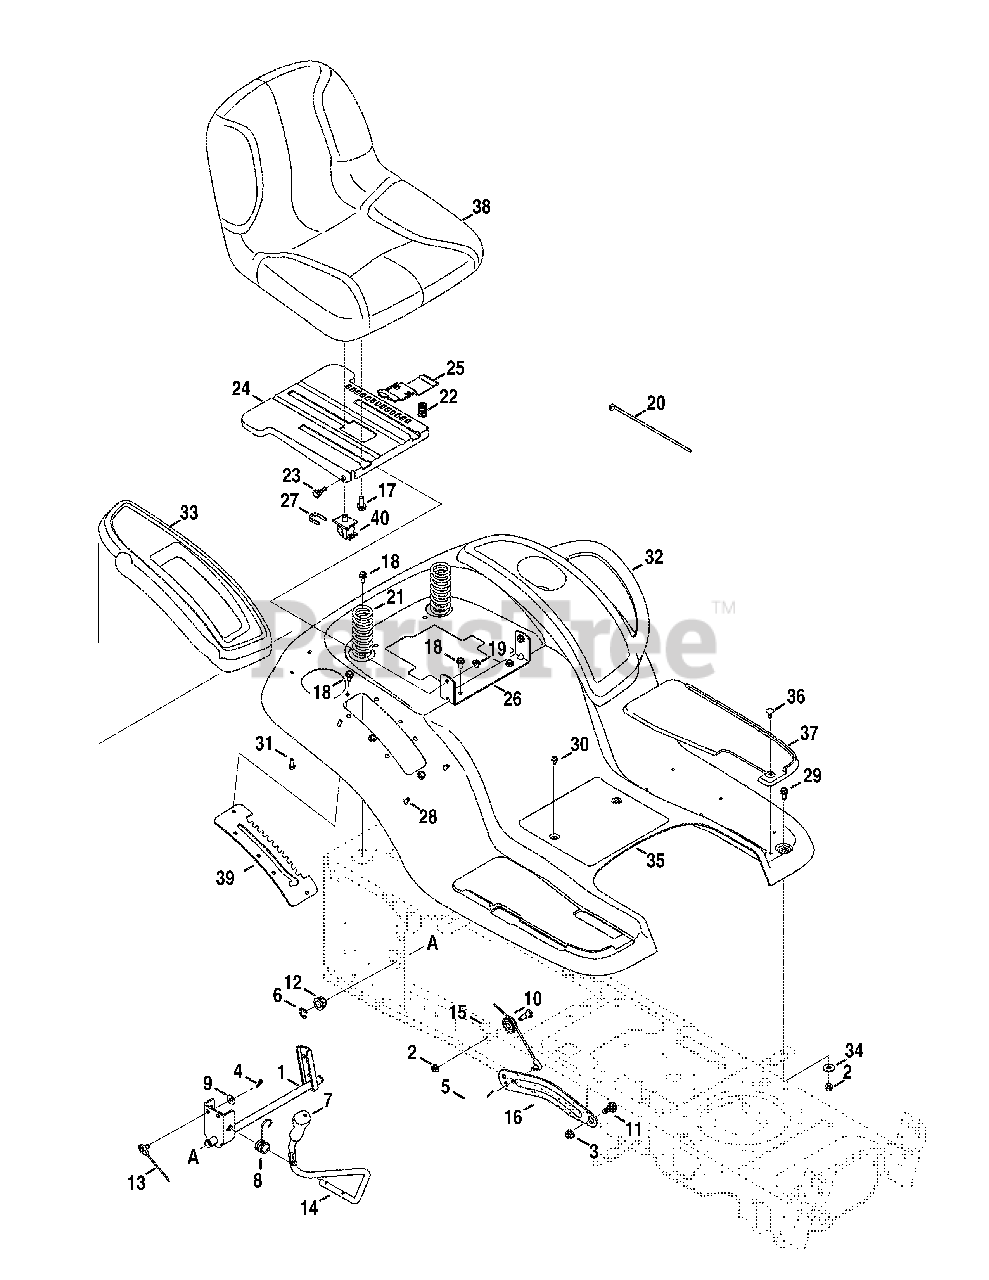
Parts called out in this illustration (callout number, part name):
1	Lift Shaft Assembly
2	Flangelock Nut, 5/16-18
3	Flangelock Nut, 3/8-16
4	Cotter Pin, .072 DIA. X 1.13 LG
5	Bow-Tie Cotter Pin
6	E-Ring, .625 DIA. SHAFT
7	Handle Grip
8	Torsion Spring
9	Spring Washer, .401 X .870 X .063
10	Shoulder Screw, .437 X .470:5/16-18
11	Shoulder Bolt, .500 x .270:3/8-16
12	Hex Flange Bearing
13	Lift Cable, 16.16 LG
14	Lift Handle
15	Pulley Roller Cable
17	Hex Head Flange, 3/8-16:.875
18	Taptite Screw, Lock Washer, 5/16-18:.750
19	Flangelock Nut, 5/16-18
20	Cable Tie, 3/16 X .05 X 7.4
21	Compression Spring, 1.71 X 3.735 X .238
22	Compression Spring, .68 X 1.065 X .055
23	Shoulder Screw, .437 X .268:5/16-18
24	Seat Mounting Bracket
25	Seat Adjustment Lever
26	Seat Pivot Bracket
27	Switch Retainer Clip
28	Hi-Lo Screw, Lock Washer, 1/4-15:0.50
29	Carriage Bolt, 5/16-18:.750
30	Taptite Screw, Lock Washer, 1/4-20:0.500
31	Hi-Lo Screw, Lock Washer, 1/4-15:0.750
32	LH Fender Cover
33	RH Fender Cover
34	Flat Washer, .344 X 1.00 X .063 HDN
36	Ratchet Clip
37	LH Foot Pad
37	RH Foot Pad
38	Seat - Sears High Back
38	Arm Rest Kit - Sears High Back Pro
38	Armrest Kit - LH w/Hardware
38	Armrest Kit - RH w/Hardware
39	Lift Bracket
40	Seat Switch
